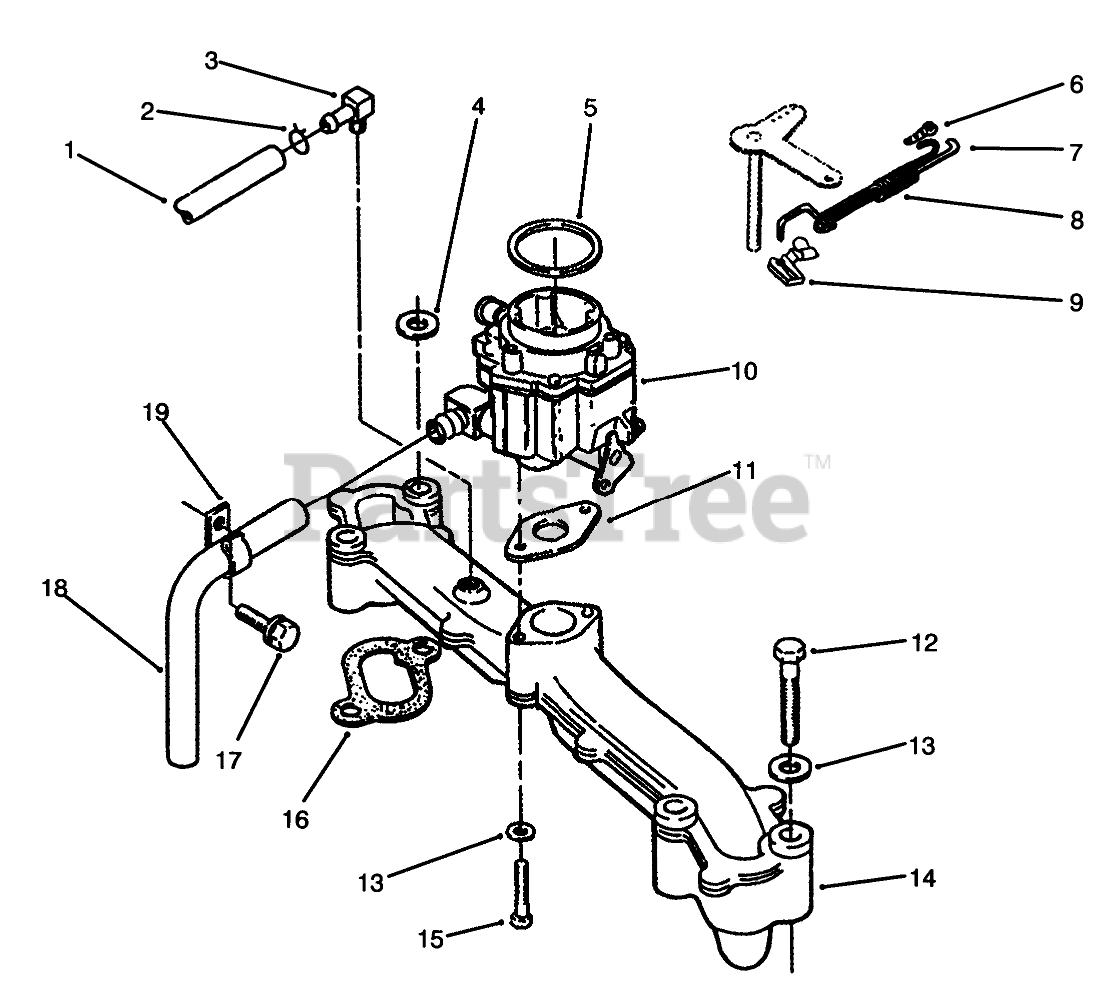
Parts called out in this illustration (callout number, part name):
1	HOSE-RUBBER, BREATHER
2	CLAMP-HOSE
2	CLAMP-HOSE, BREATHER
3	FITTING-BARB
4	FLAT WASHER
7	Governor Control Rod
8	Spring-Governor Rod
10	Assembly-Carburetor (Incl. Ref. #5 & 11)
11	GASKET-CARBURETOR
13	WASHER-FLAT
14	MANIFOLD
15	HEX-HEAD CAP SCREW
16	GASKET
17	SCREW-HWH
18	FUEL HOSE
19	Clip
